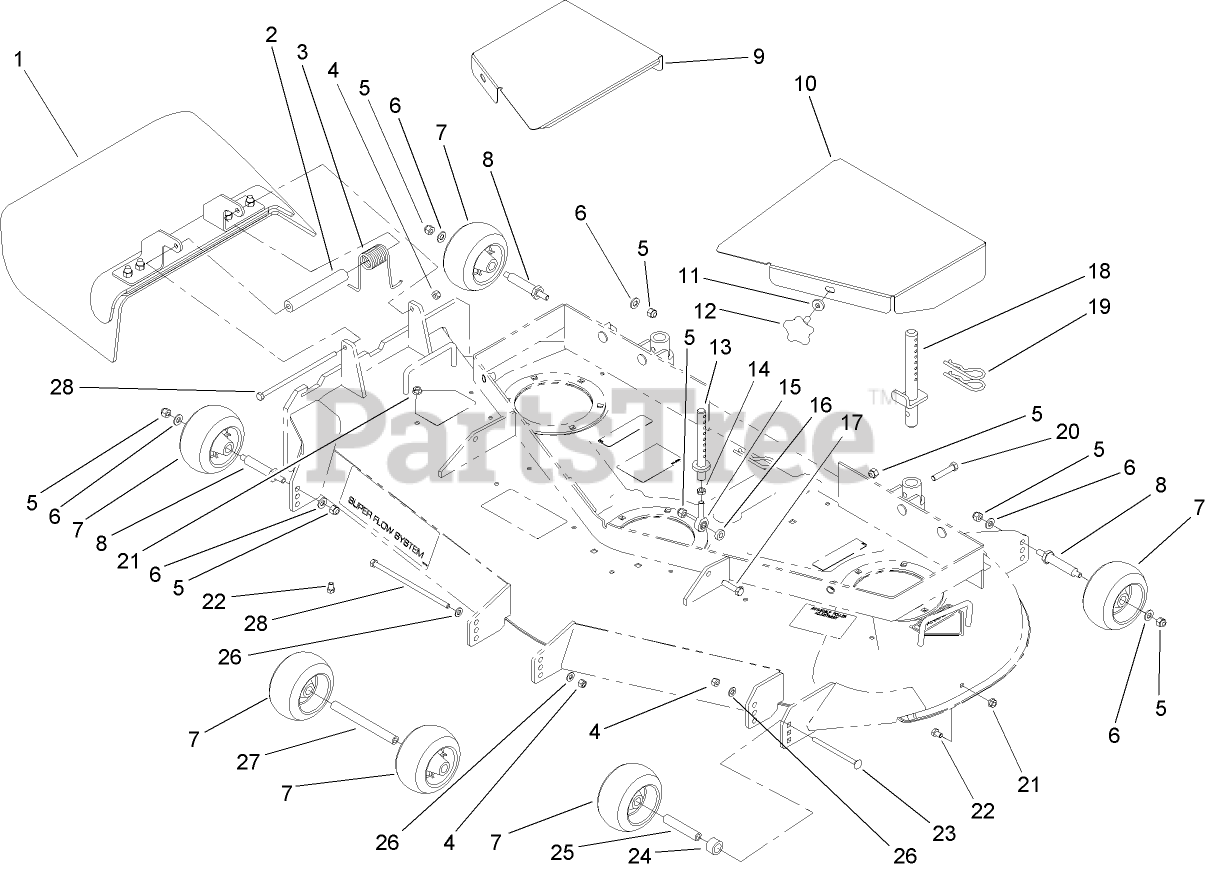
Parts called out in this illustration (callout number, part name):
1	DEFLECTOR ASM
2	SPACER
3	SPRING-TORSION
4	NUT-LOCK, NI
5	NUT-LOCK, NI
6	WASHER-FLAT
7	ROLLER-SCALP, ANTI
8	SPACER
9	COVER-BELT, RH
10	COVER-BELT, LH
11	WASHER-RUBBER
13	FRONT PIN ASM
14	NUT-HJ
15	BALLJOINT
16	SPACER
17	SCREW-HH
18	REAR PIN ASM
19	PIN-HAIR
20	SCREW-HH
21	NUT-HF
22	SCREW-HH
23	SCREW-CARR
24	SPACER-WHEEL
25	BUSHING-ROLLER
26	WASHER-PLAIN
27	SPACER-WHEEL
28	SCREW-HH
